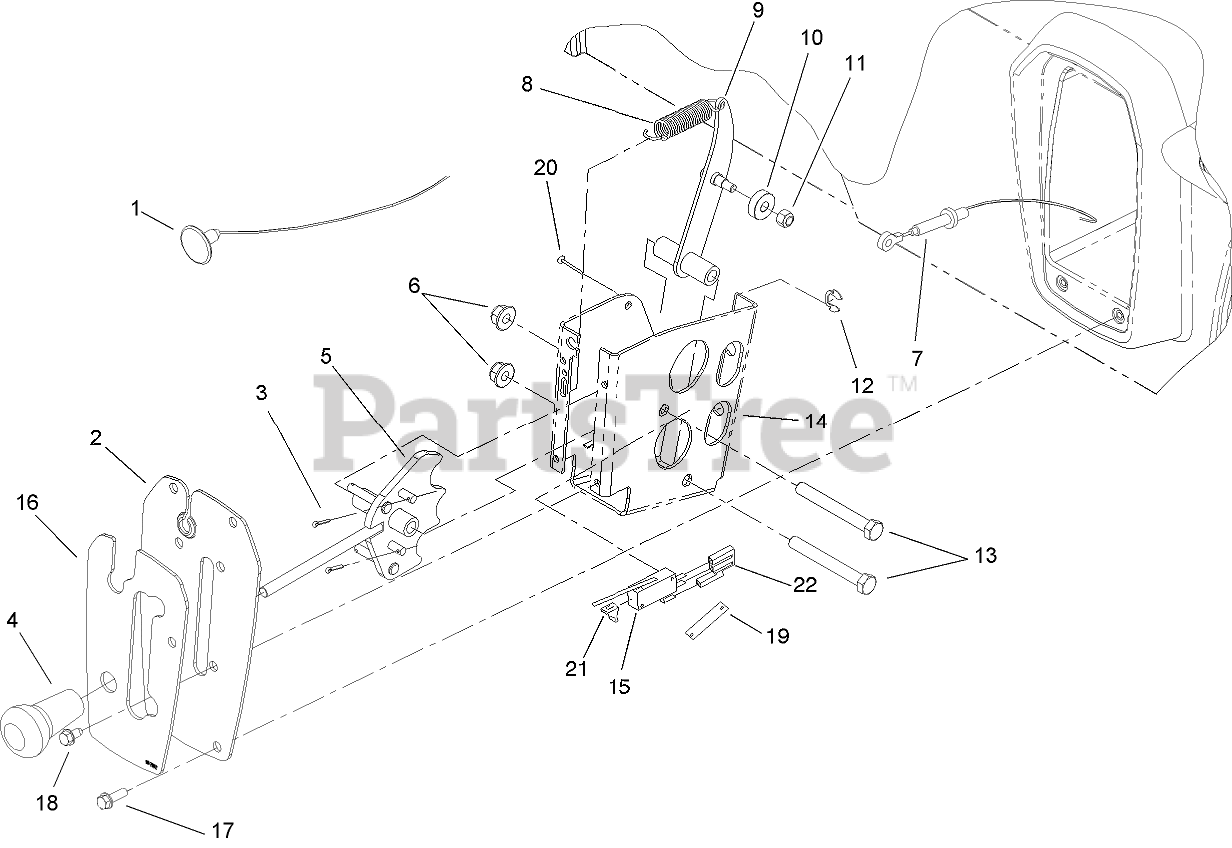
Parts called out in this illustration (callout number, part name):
1	CABLE-CHOKE
2	PLATE-SHIFTER
3	PIN-COTTER
4	KNOB-GRIP, SOFT
5	LEVER-SHIFT
6	NUT-HF, NI
7	Cable-Shift
8	SPRING-RETURN, PEDAL
9	ARM-DETENT
10	BEARING-BALL
11	NUT-LOCK, NI
13	SCREW-HH
14	BRACKET-SHIFT
15	SWITCH-MICRO
16	DECAL-SHIFTER
17	SCREW-HWH
18	SCREW
19	NUT-SPEED
20	SCREW-SPH
21	PLUNGER-SEAL
22	HARNESS-JUMPER, SHIFT
